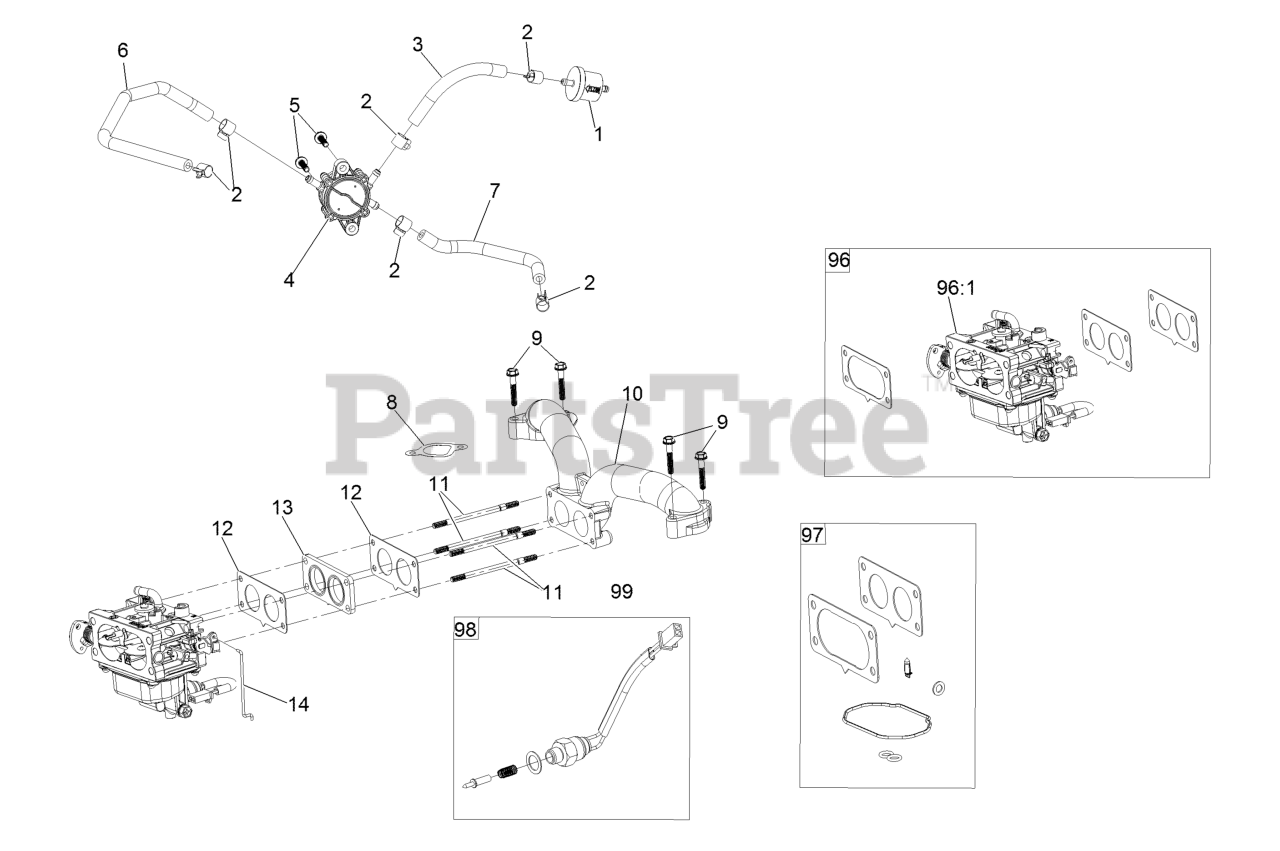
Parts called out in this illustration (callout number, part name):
1	Filter-Fuel
2	Clamp-Fuel Line
3	Line-Fuel
4	Pump-Fuel
5	Screw-HHF
6	Hose-Fuel
7	Hose-Fuel
8	Gasket-Intake
9	Screw-HHF
10	Manifold-Intake
12	Gasket-Carburetor
13	Insulator-Carburetor
14	Linkage-Throttle
96	Carburetor Replacement Kit
96:1	Carburetor
97	Carburetor Repair Kit
98	Solenoid Kit
99	High Altitude Kit
